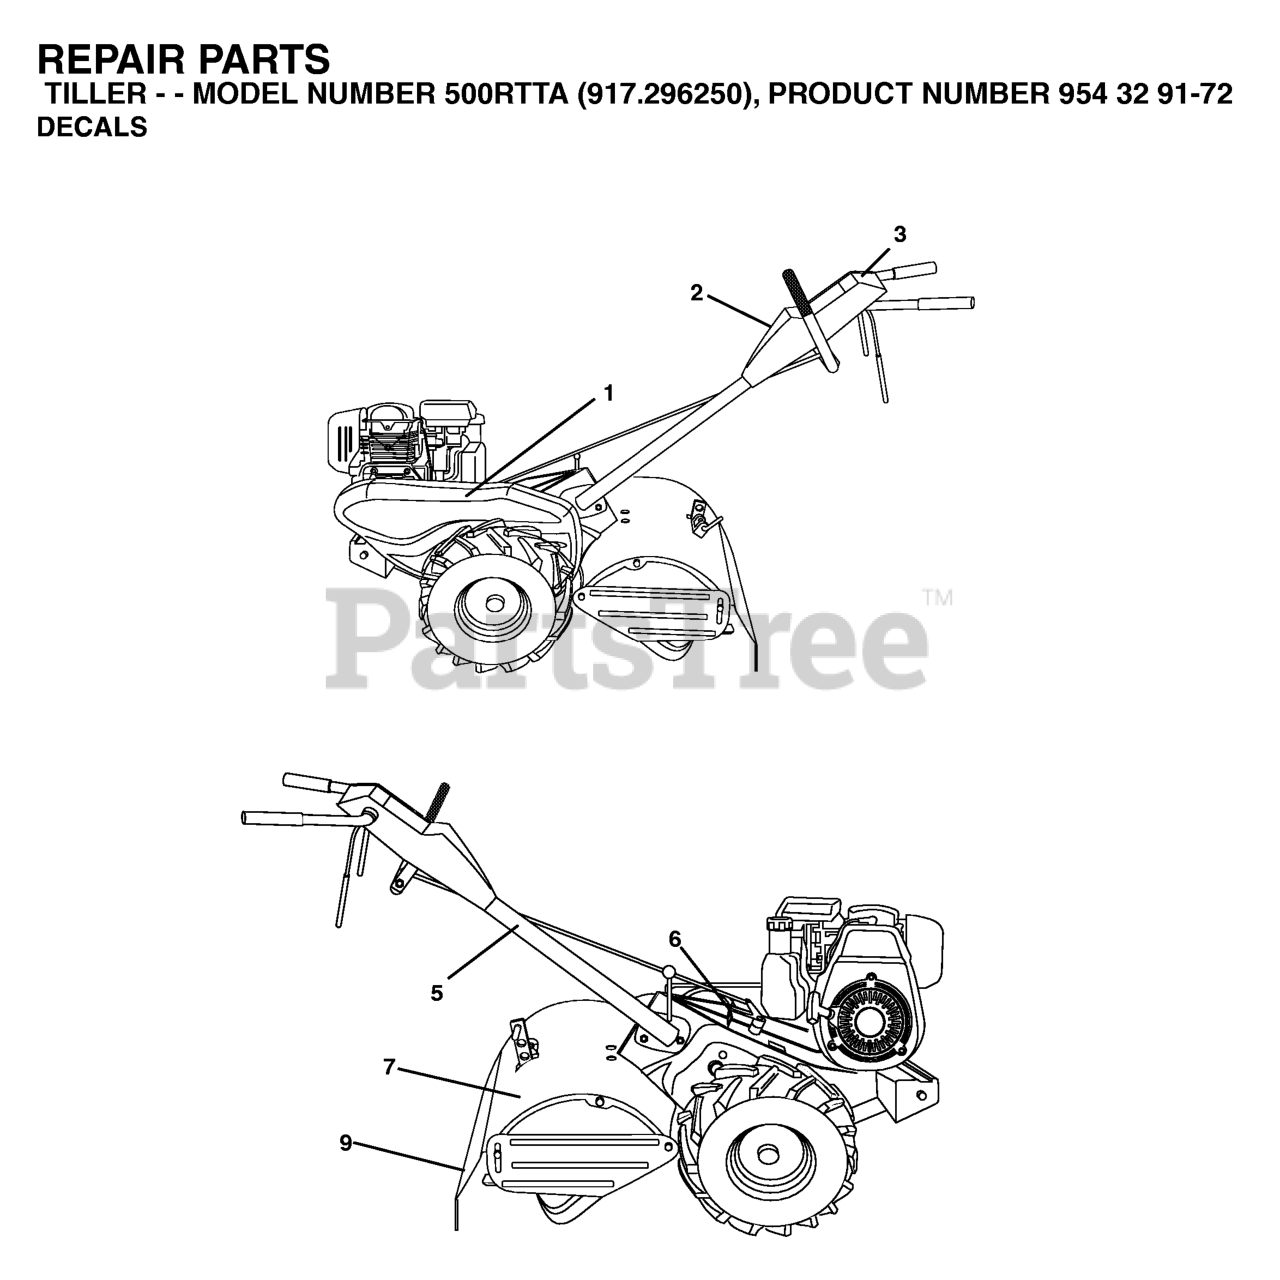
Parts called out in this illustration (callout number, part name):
1	DECAL, BELT GUARD
2	DECAL, CONTROL PANEL
3	DECAL, LOGO
5	DECAL TI (2 2)
6	DECAL.SHIFT.INDICATOR.TILLER
7	DECAL -CAUTION
9	DECAL TI
